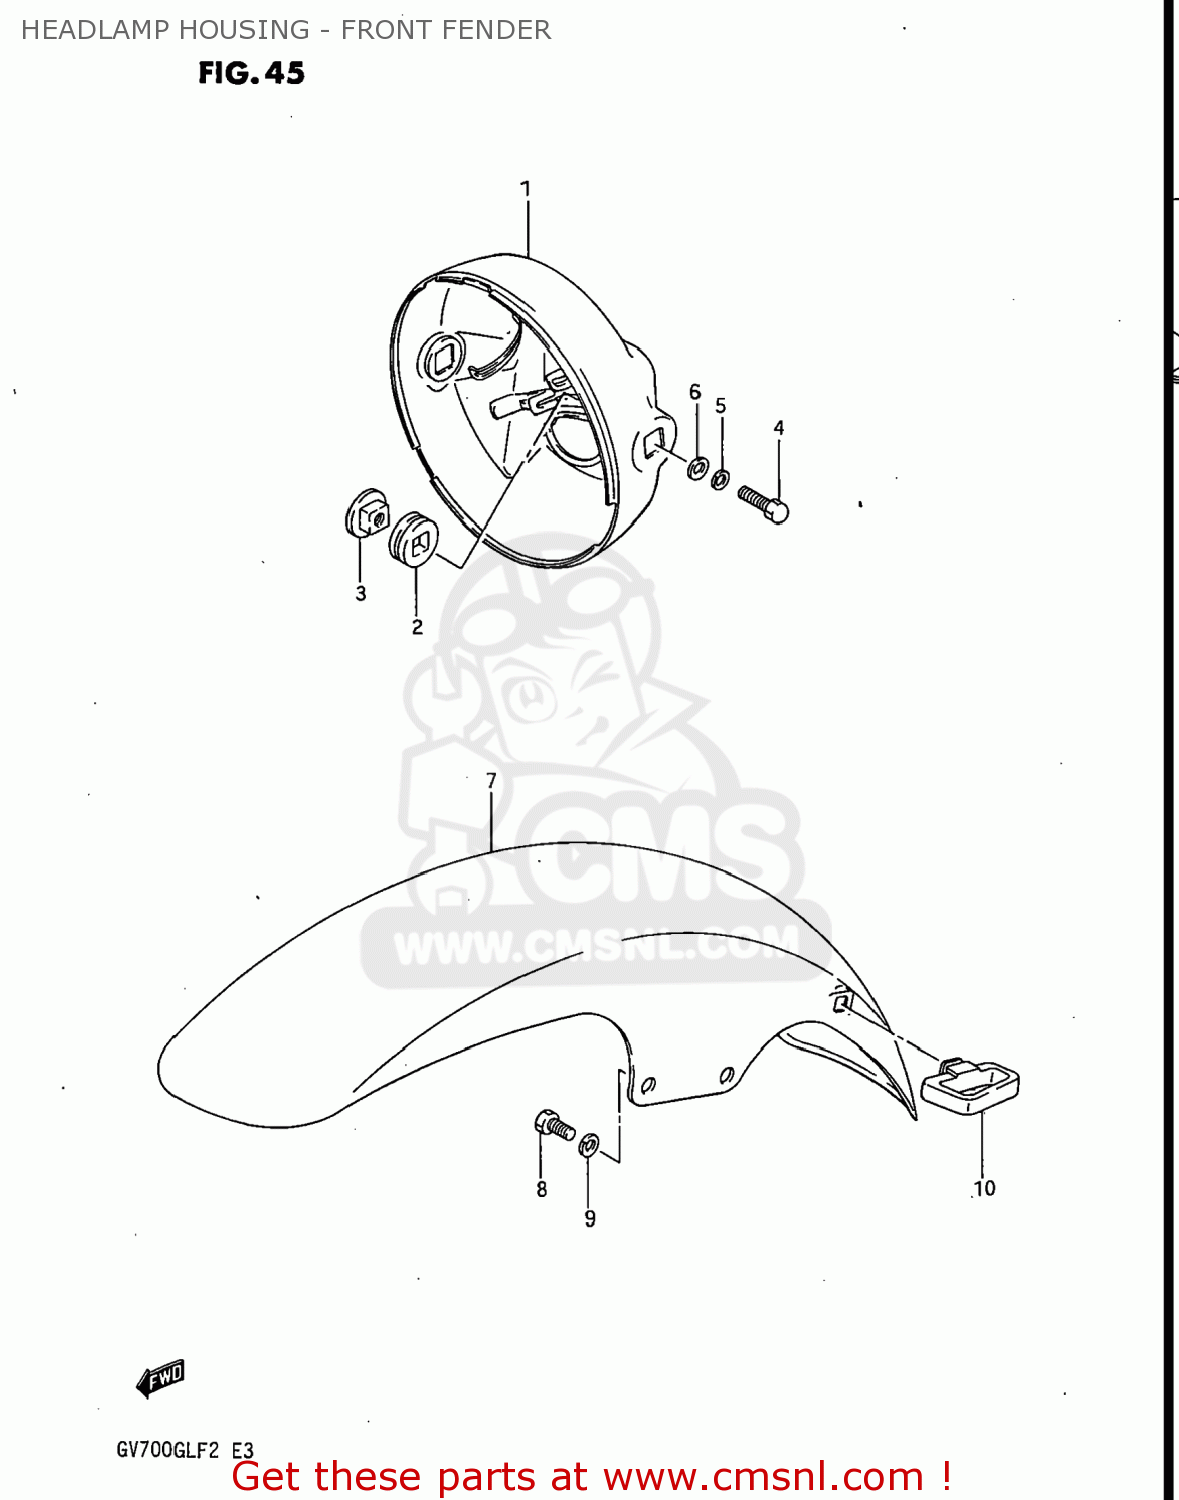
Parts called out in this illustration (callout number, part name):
1	HOUSING,HEADLAMP (COWLING)
2	CUSHION,HEADLAMP HOUSING
3	SPACER,HEADLAMP HOUSING
4	BOLT
5	LOCK WASHER
6	WASHER
7	FENDER,FR
8	BOLT
9	LOCK WASHER
10	GUIDE,CABLE
